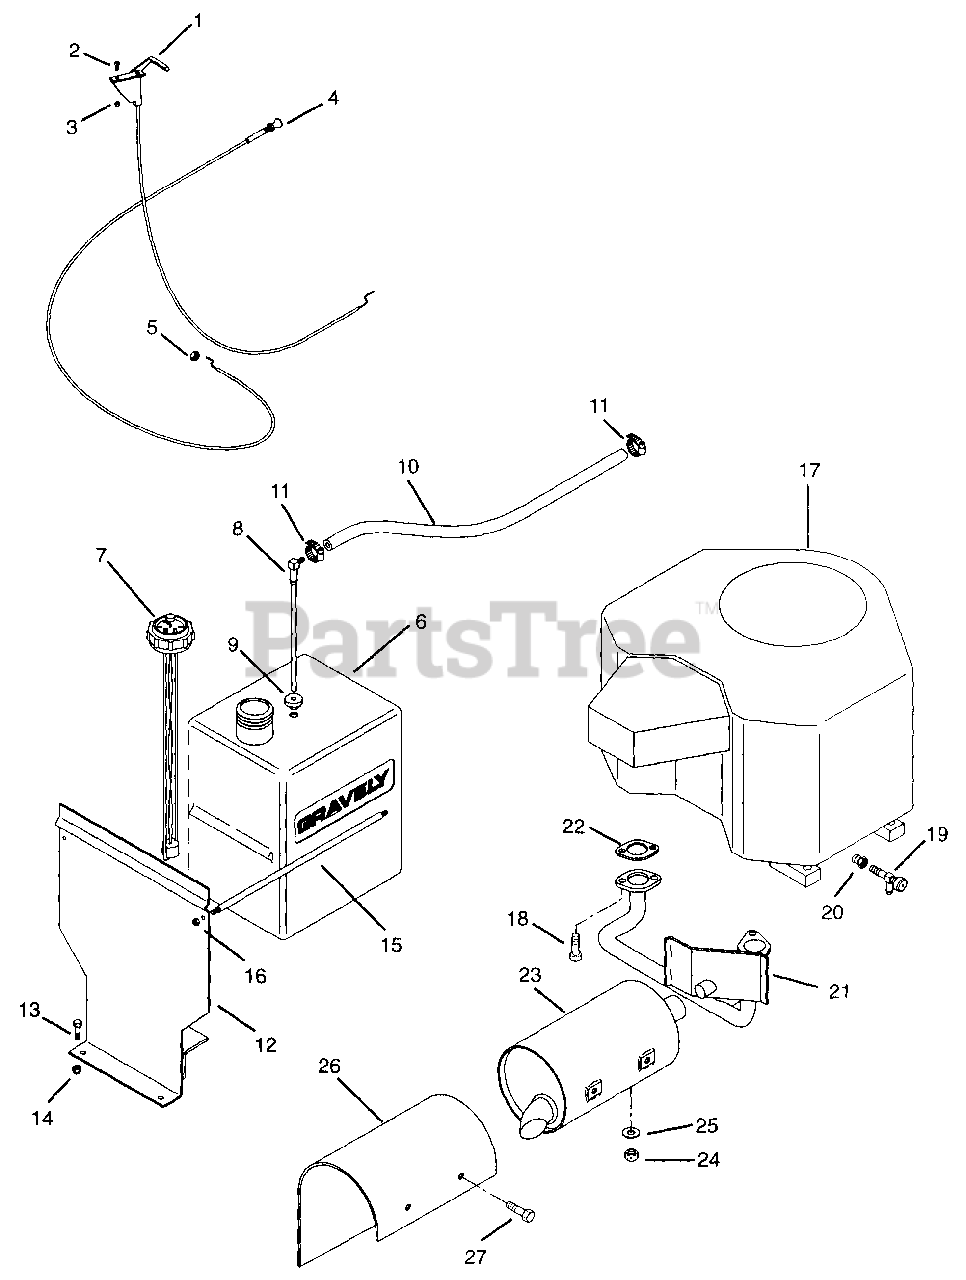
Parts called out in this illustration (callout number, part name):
1	Throttle Cable
2	Screw-Machine 10-24 x .50
3	Nut-Locking 10-24
4	Control, Choke (008)
4	Control, Choke (007,011)
5	Nut-Jam .375-24
6	Tank, Fuel
7	Gauge, Fuel
8	Fitting, Tank
9	Bushing
10	Gas Line-Bulk
11	Hose Clamp
12	Weldment, Tank Bracket
13	Bolt-Hex .31-18 x .88 Grade 5
14	Nut-Locking-Nylon .312-18 Grade 2
15	Rod, Tank
16	Nut-Locking-Nylon .250-20 Grade 2
17	Engine, Kohler CV 18 HP (007)
17	Engine, Kohler CV20 (008)
17	Engine, Kohler CV 25 HP (011)
18	Screw-Socket Head M8-1.25 x 20 mm
19	Cock, Oil Drain
20	Adapter, Oil Drain
21	Manifold, Kohler CV18-25
22	Gasket, Exhaust
23	Muffler (Includes 09066300 Heat Shield)
24	Nut-Locking-Center .38-16
25	Washer-Flat-Steel .438 x 1.00 x .083
26	Heat Shield (Included with 09065600 Muffler)
27	Screw-Tapping w/Washer
